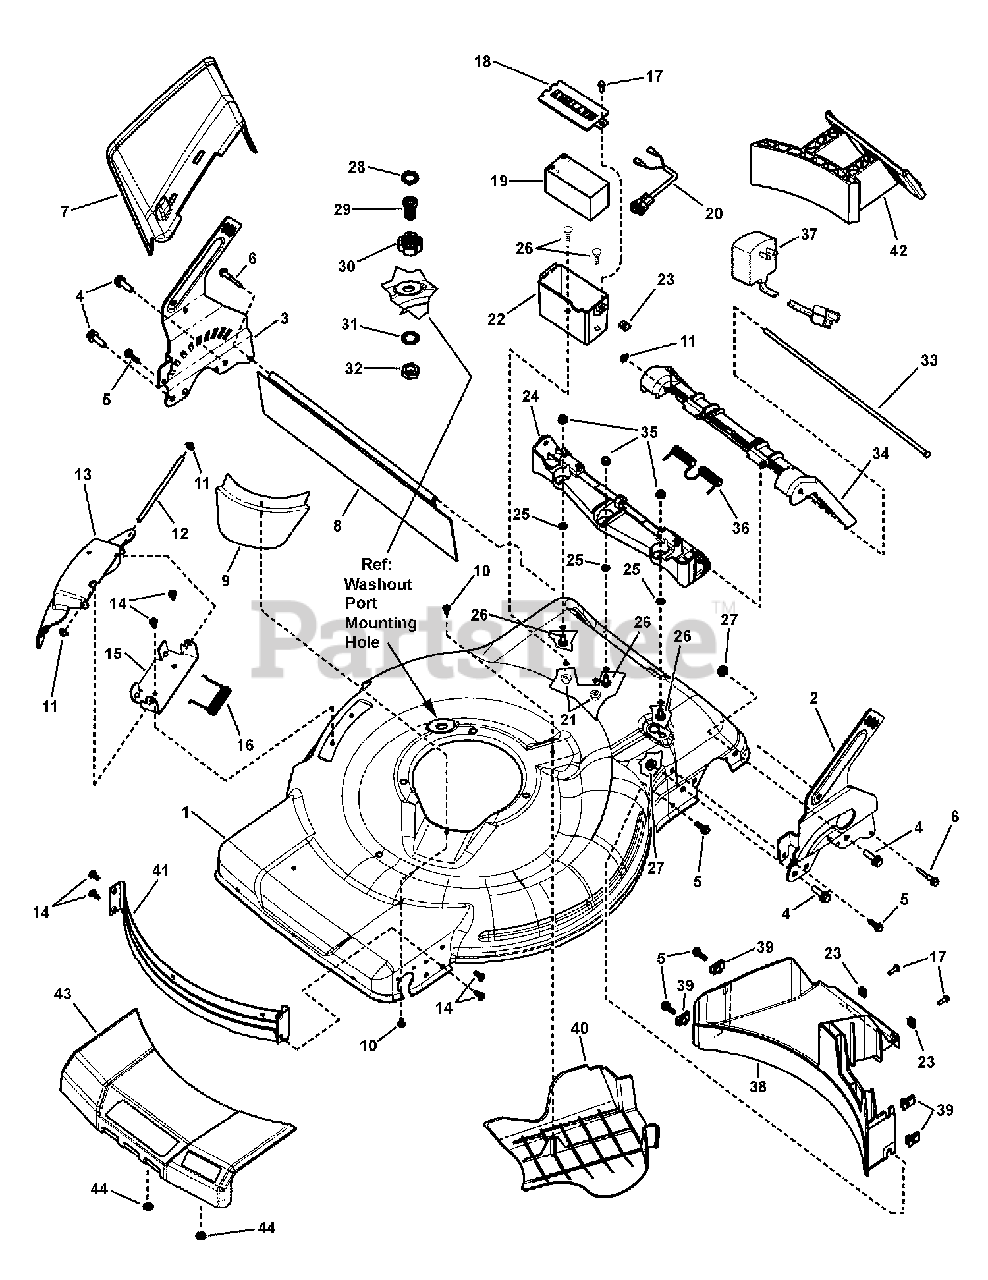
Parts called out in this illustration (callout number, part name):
1	DECK, 22, Rear Wheel Drive, Washout
1	DECK, 22", Snapper Rear Wheel Drive, Electric Start
2	BRACKET, Rear Wheel, LH, Quick Adjust
3	BRACKET, Rear Wheel, RH, Quick Adjust
4	BOLT, 5/16-18 x 1" Hex Flange Lock, Grade 5
5	CAPSCREW, Hex Flange Lock, 1/4-20 x 3/4, G5
6	BOLT, Drag Shield, 1/4-20 x 1-1/2"
7	CHUTE, Side Discharge, WBM, 22"
8	GUARD, Rear, 22"
9	SHIELD, Debris, Front
10	SCREW, Torx, Hi-Lo
11	PUSH-NUT, 1/4"
12	ROD, Pivot (1/4" Dia. x 5.55")
13	COVER, Mulching
14	SCREW, 1/4-20 x 1/2" Pan Head Self-Tap (Torx)
15	BRACKET, Chute
16	SPRING, Torsion, Chute
17	SCREW, #10-24 x 5/8" Slotted Hex Washer Head Self-Tap
18	TOP, Battery Box, Miniature
19	BATTERY, 12V, 1.3 A/HR, Type G Terminals
20	HARNESS, Battery, 1.3 A/HR
21	NUT, Hex Flange, 1/4 - 20
22	BOTTOM, Battery Box, Miniature
23	NUT, Retainer, Speed #10-24 w/Extrusion
24	HINGE, Door, Rear Discharge
25	NUT, PUSH FOR .250 DIA THREAD .500 OD BLK
26	SCREW, 1/4-20 x 5/8" Flat Head Square Neck, Grade 2
27	NUT, 5/16-18 Hex Flange Lock GR 5
28	WASHER, Hose
29	ADAPTOR, Washout Port, WBM
30	COUPLING, Hose
31	WASHER, 5/8" Internal Tooth Lock
32	NUT, 5/8-11, NC-2B Black Hex Jam
33	ROD, Pivot, Rear Door
34	DOOR, Rear Discharge
35	NUT, Bi-Way Lock, 1/4-20
36	SPRING, Rear Door (Torsion)
37	CHARGER, Battery, 120V AC, Output 14V DC, 260mA
38	BAFFLE, Rear, Rear Wheel Drive WBM
39	U-NUT, 1/4-20 Locking
40	COVER, Belt Drive, Rear
41	BAFFLE, Front, Galv.
42	PLUG, Mulching, 22" Deck
43	COVER, Front, Push/Rear Wheel Drive
44	NUT, 3/16" Push
